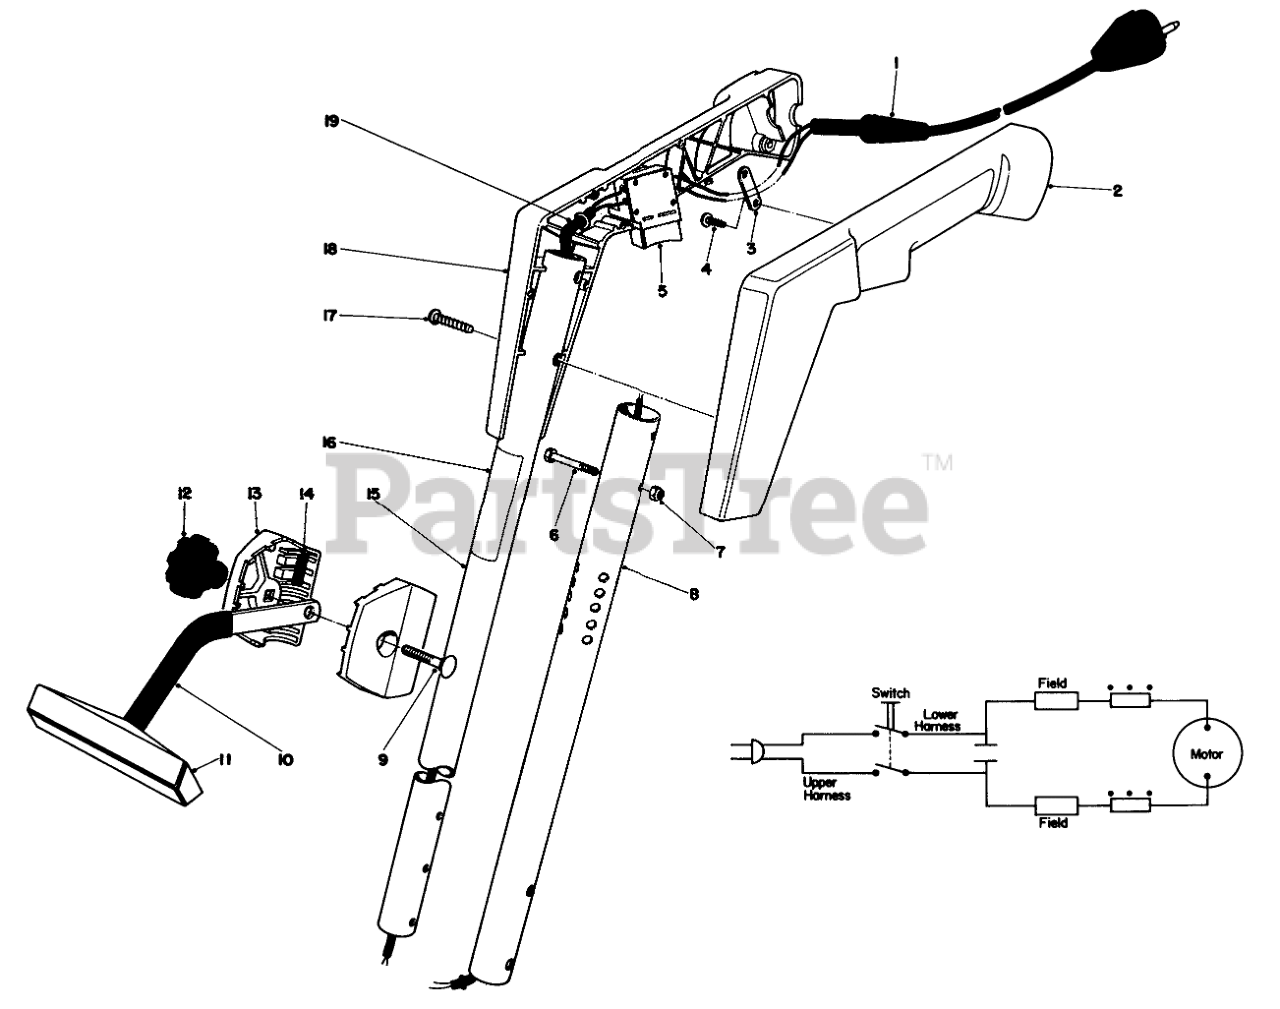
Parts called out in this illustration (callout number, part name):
4	SCREW-PPH
7	NUT-LOCK, NI
9	BOLT-CARR
